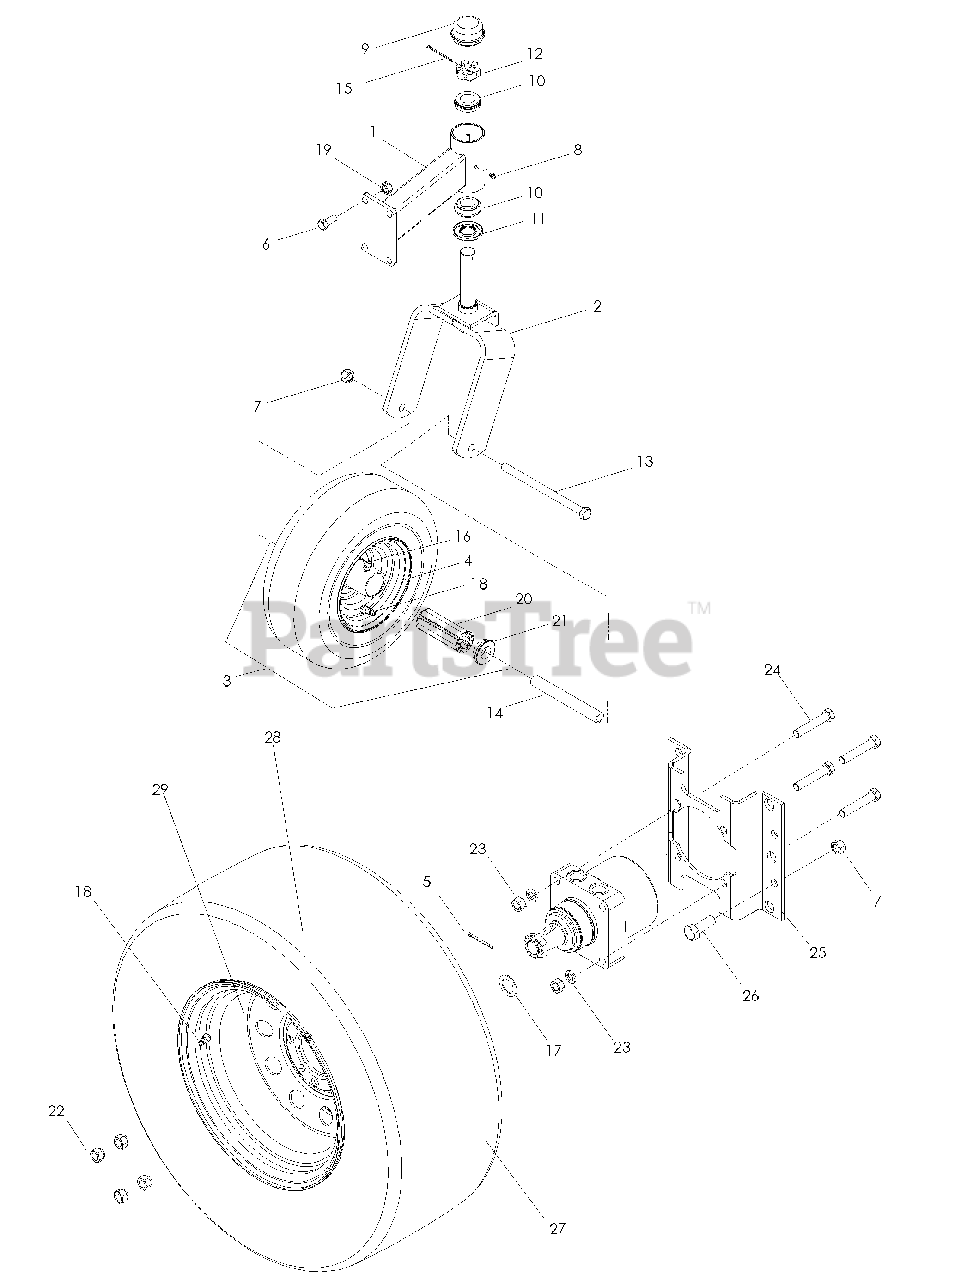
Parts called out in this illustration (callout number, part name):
1	CASTER ARM
1	CASTER ARM MODEL 968999708
2	CASTER YOKE
3	TIRE ASSEM
4	RIM
5	COTTER PIN
6	HCS 7/16-14 x 1
7	NUT 1/2 -13 HEX NYLOC
9	CAP GREASE
10	BEARING, TAPERED
12	NUT 1-14 JAM SPEC
13	HCS 1/2-13 x 7 1/2
15	PIN, COTTER, 1/8 x 2
17	BUSHING, 1"
18	VALVE STEM
19	NUT 7/16-14 HEX CTRLK GR A
20	BEARING, ROLLER 2 1/2
21	BEARING, FLANGED
23	LOCKWASHER 1/2
24	HCS 1/2-13 x 2 3/4
25	MOTOR STANDOFF
26	HCS 1/2-13 x 1/4
27	TIRE ASSEMBLY MODELS iZ4821BF, iZ5225XPBF
27	TIRE ASSEMBLY MODELS iZ25, iZ4821, iZ5223VAN, i5223
27	TIRE ASSEMBLY MODELS iZ4217, iZ4819, iZ4217C
27	TIRE ASSEMBLY MODELS iZ6125
28	TIRE MODELS iZ4217, iZ4819, iZ4217C, iZ6125, iZ4821BF, iZ5225XPBF
28	TIRE MODELS iZ25, iZ4821, iZ5223VAN, i5223
29	RIM MODELS iZ4821BF, iZ5225XPBF
29	RIM MODELS iZ25, iZ4821, iZ5223VAN, i5223
29	RIM MODELS iZ4217, iZ4819, iZ4217C
29	RIM MODELS iZ6125
